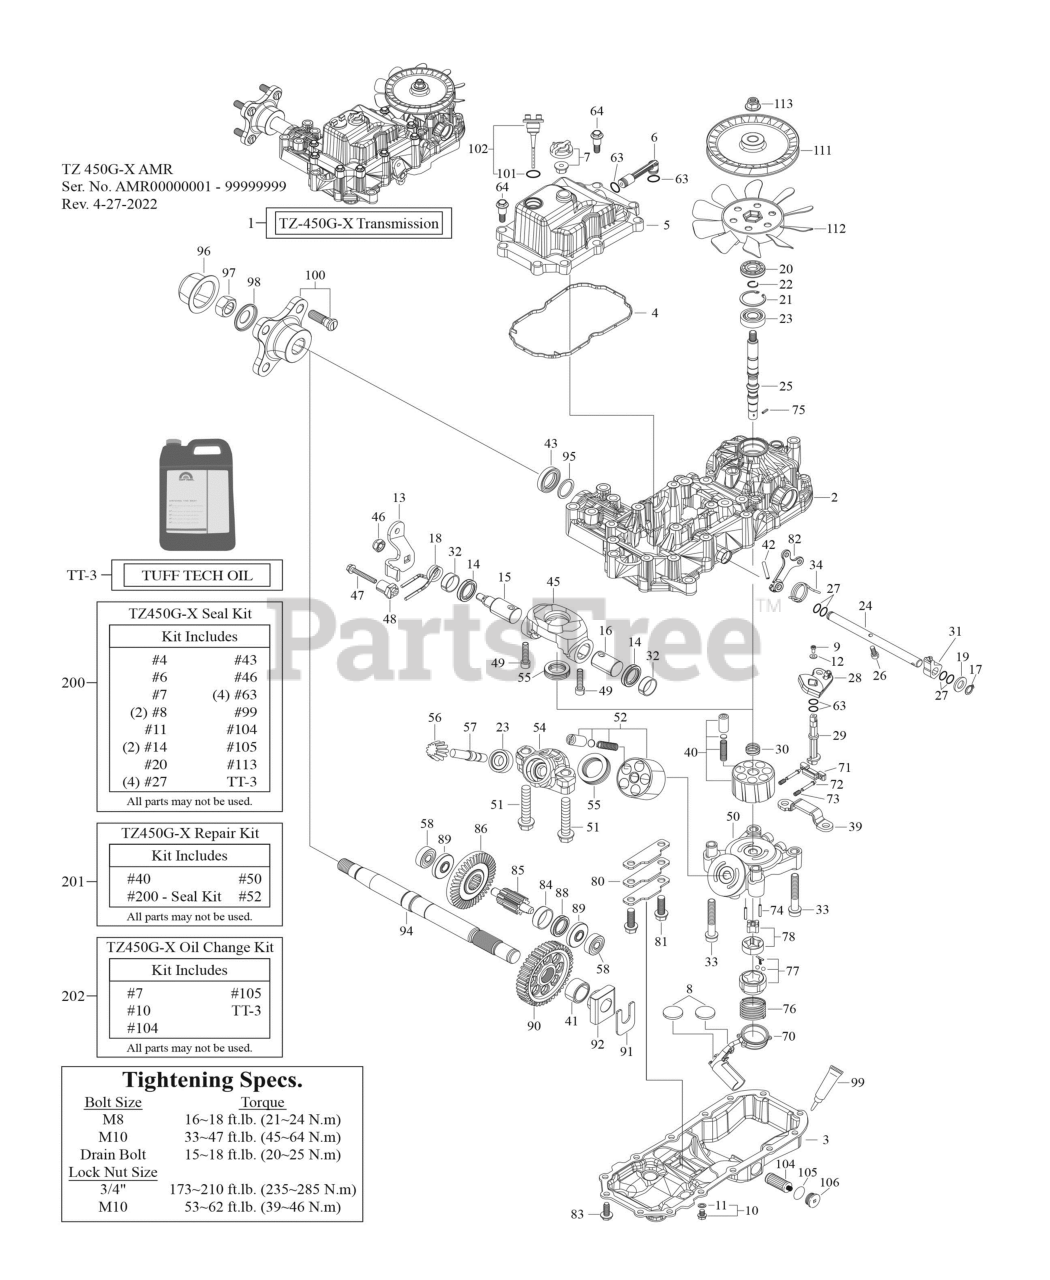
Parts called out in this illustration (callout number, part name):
1	HYDRO TRANSMISSION (LH)
2	UPPER HOUSING X
3	LOWER HOUSING FY
6	BYPASS PIPING
10	DRAIN BOLT KIT
11	WASHER-SEAL DRAIN BOLT
12	WASHER 4.5X10X1
13	CONTROL LEVER X
15	CONTROL SHAFT
16	CONTROL SHAFT SHORT
18	TORSION SPRING
19	FLAT WASHER 12
20	SEAL-OIL 15X35X07
23	BALL BEARING
26	SOCKET BOLT 6X16
30	SPRING-CYL BLOCK
31	BRAKE FORK 20 CR
32	CONTROL BUSH LFB2510
33	HEX BOLT M10X65
34	SPRING, BRAKE XA
39	CHECK STOPPER PFG
40	CYLINDER BLOCK KIT
42	SPRING PIN 5 x 3
43	SEAL TC284008
50	CENTER CASE
52	BLOCK KIT-PISTON & MOTOR
54	MOTOR HOUSING A
55	THRUST BEARING
58	BEARING 6201 CN
64	TAP SCREWPING 8X
70	BRACKET ASSY FT3
73	BYPASS SPRING
75	PIN 2.5 x 9.8
76	SPRING-CHARGE PUMP
77	PUMP CASE ASSEMBLY
83	TAP SCREWPING
84	FINAL PINION COLLAR
85	FINAL PINION SHAFT
86	REDUCTION GEAR
88	REDUCTION COLLAR
89	WASHER 14.1X30X3.5
97	LOCK NUT 3/4-16
98	FLANGE SPACER
105	RING-"O" LWR CASE CAP
113	NUT-LOCK PMP SHAFT
200	SEAL KIT W/OIL
201	REPAIR KIT W/OIL
202	OIL CHANGE KIT (TZ-450)
TT-3	TUFF TECH OIL 3 LITER BOTTLE
